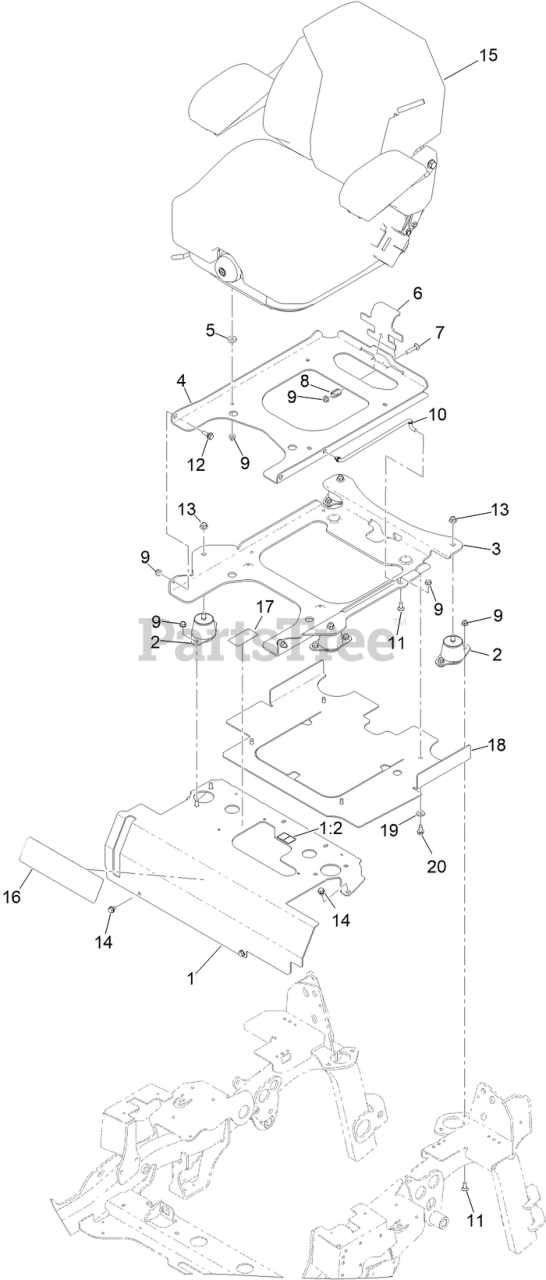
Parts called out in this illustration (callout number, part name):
1	MOUNT-SEAT W/DECALS
1:2	DECAL-WARNING
2	ISOLATOR-SEAT
3	PLATE,TILT SEAT SUPPORT
4	PLATE-FRAME, SEAT
6	PLATE, SEAT LATCH
7	BOLT-CARR
8	SPRING-COMPRESSION
9	NUT-HF, NI
10	ROD-PROP
11	SCREW-CARR
12	SCREW-SHOULDER
13	NUT-HF, NI
14	SCREW
15	ASM-SUSPENSION SEAT, TORO
16	DECAL-CONSOLE
17	DECAL-FLUID, TRANSMISSION
18	SHIELD-HEAT
19	WASHER-FLAT
20	SCREW-HWHTF
